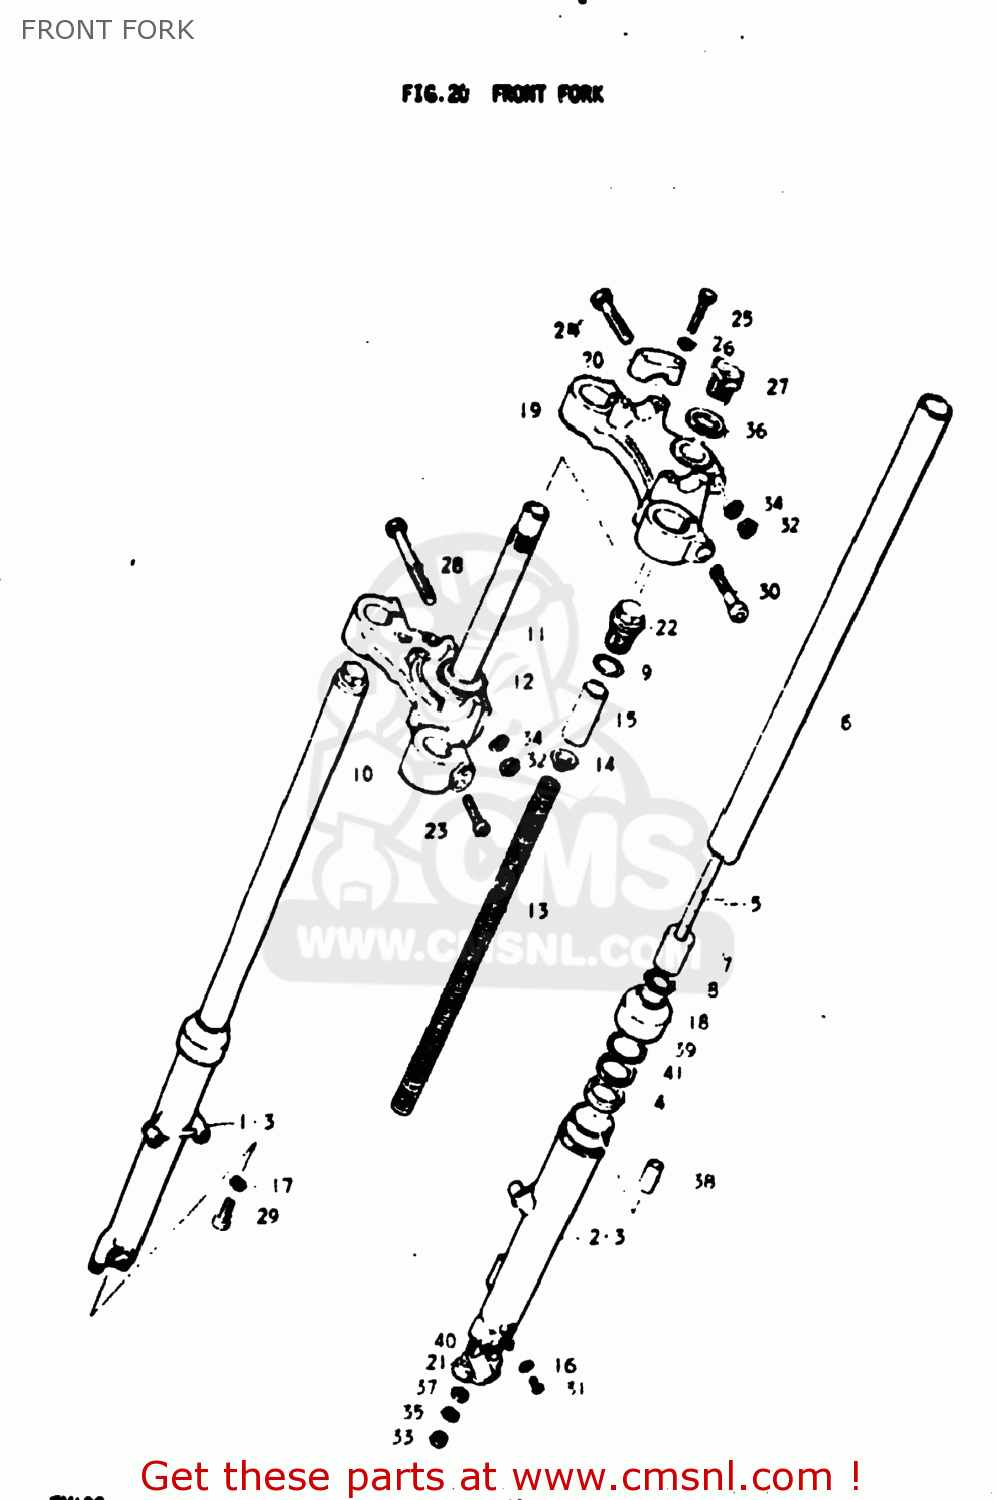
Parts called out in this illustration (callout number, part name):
1	TUBE,OUTER,RIGHT
2	TUBE,OUTER,LEFT
3	TUBE,OUTER,LEFT
4	SEAL,OIL
5	CYLINDER,FRONT FORK
6	TUBE,FORK,INNER
7	PISTON
8	SNAP RING
9	O-RING,FORK INNER TUBE
10	STEM,STEERING
11	STEM,STEERING
12	RACE,STEERING OUTER LWR
13	SPRING
14	GUIDE,SPRING
15	SPACER,SPRING
16	GASKET,DRAIN,PLUG (NAS)
17	GASKET
18	SEAL,DUST
19	HEAD,STEERING STEM
20	HOLDER,HANDLEBAR
21	HOLDER,AXLE
22	BOLT,FR FORK
23	BOLT
24	BOLT 10X50
25	Bolt
26	LOCK WASHER
27	CAP
28	BOLT
29	BOLT
30	BOLT
31	SCREW
32	NUT
33	NUT (8MM)
34	LOCK WASHER
35	LOCK WASHER
36	WASHER,STEM HEAD
37	WASHER
38	PIECE,OIL LOCK
39	RING,SNAP
40	BOLT,STUD
41	WASHER,FRONT FORK
